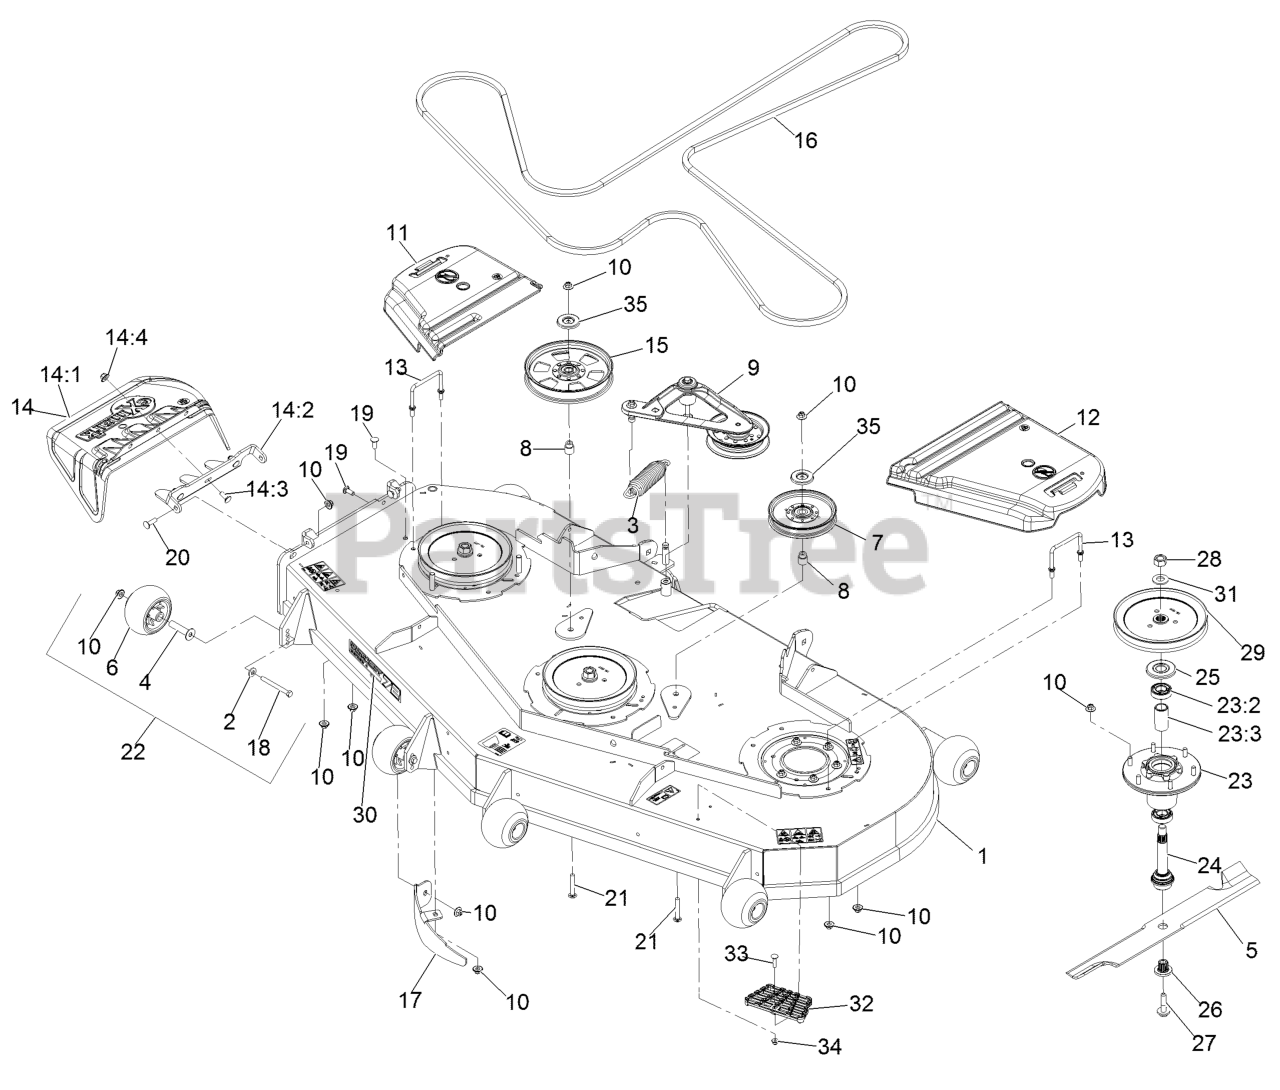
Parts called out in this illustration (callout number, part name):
1	ASM,Deck W/Decals 724
2	Washer-Spring Disc 3/8
3	Spring-Extension
4	Axle, Roller
5	Blade, Solid (72")
5	Blade, Low Lift (72")
5	Blade, Mulching (72")
5	Blade, Notched (72")
5	Blade-Extreme 2, 24.50"
6	Roller-Anti-Scalp
7	Idler-Pulley, Flat 6.00X0.75
8	Bushing, Idler
9	Deck Idler ASM
10	Nut-Nyloc 3/8-16 Flg
11	Cover-Belt, RH
12	Cover-Belt, LH
13	Wireform-Cover
14	ASM,Discharge Chute
14:1	Chute, Discharge
14:2	Bracket,Discharge Chute
14:3	Bolt-Carriage 3/8-16 X 1
14:4	Nut-Nyloc 3/8-16 Flg
15	Pulley-Idler, Flat
16	Belt,V-5V X 219.00"
17	Baffle-Dogleg, Lz72
18	Screw-HH 3/8-16 X 3 3/4 Gr 8
19	Bolt-Carriage 3/8-16 X 1
20	Bolt-Carriage 3/8-16 X 1 1/4
21	Bolt-Carriage 3/8-16 X 2 1/2
22	Kit, Anti-Scalp Roller
23	ASM-Cutter Hsg With Bearings
23:2	Bearing-Ball
23:3	Spacer-Bearing
24	ASM-Spindle And Seal
25	Guard,Bearing Top .989
26	Bushing, Splined
27	Screw-Sems 1/2-20 X 2.19
28	Nut-Hex
29	Sheave,Blade Drive 8.74
30	Decal, 724
31	Washer-Spring Disc 3/4
32	Step-Deck
33	Screw-CARR
34	Nut-Flange, NI
35	Shield-Dust
